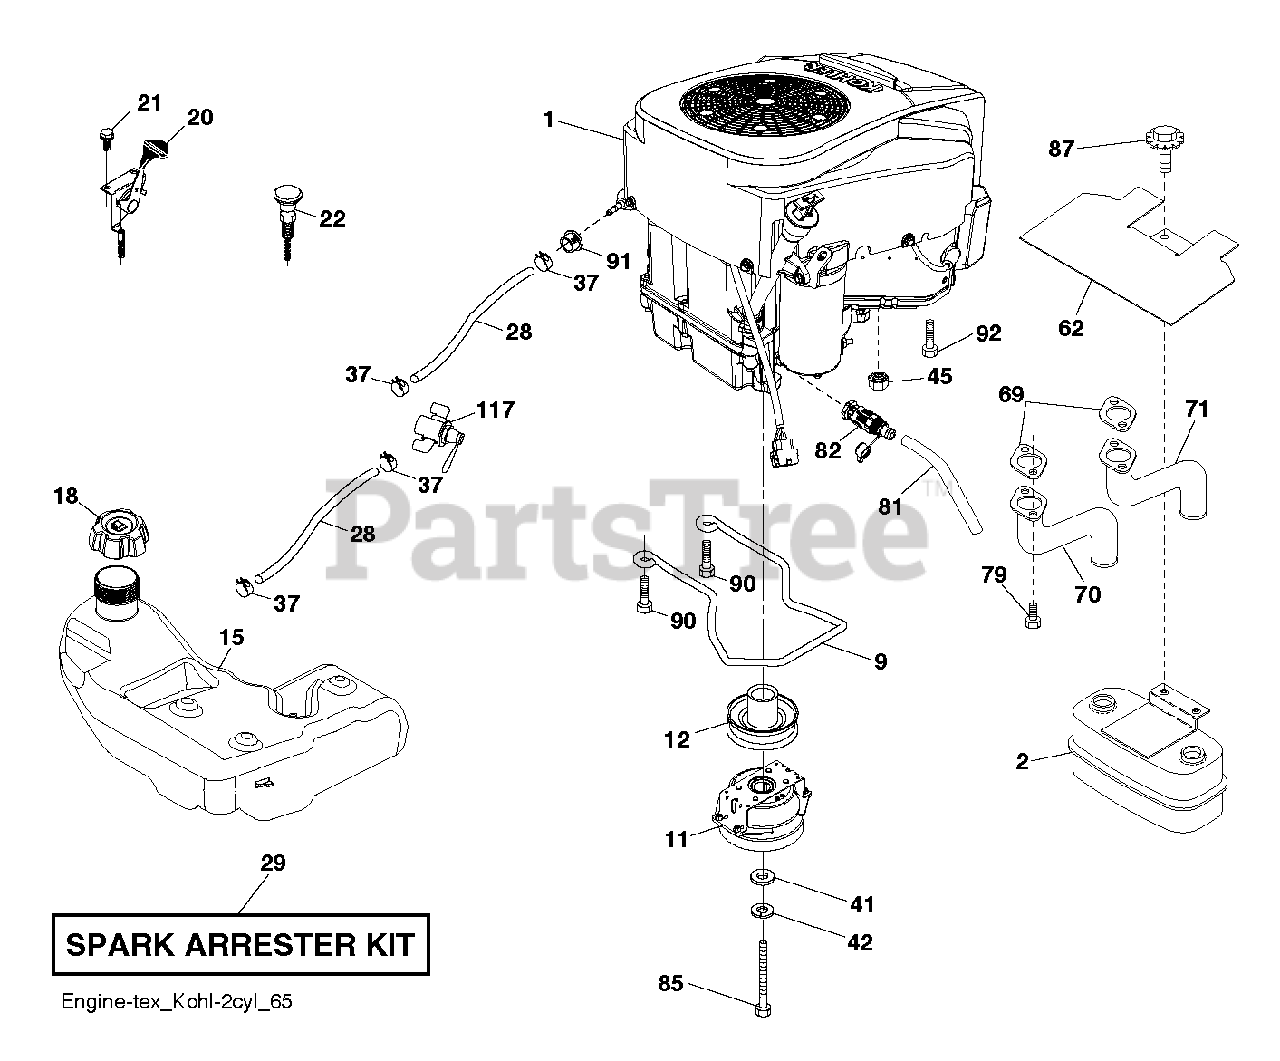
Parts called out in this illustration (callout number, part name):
2	MUFFLER.ASM.TWN.EXTNDED.DFLCTR
9	KEEPER BELT ENGINE
11	CLUTCH.OGURA.5.0PD.GT1.5A-EH01
12	PULLEY ENGINE
15	TANK.ASSY.4.GAL.2.PORT.EPA
18	CAP ASSY FUEL 3" BLACK
20	THROTTLE CONTROL
21	SCREW.#10 X 0.750.BOS
22	CONTROL.CHOKE.ERGO.PUSH-IN.BLA
28	LINE.FUEL.64"REAR.EMIS
29	KIT.SPARK ARRESTOR 794945 B&S
37	HOSE CLAMP
42	LOCKWASHER
45	NUT
62	SHIELD.HEAT.MUFFLER
69	GASKET.EXHAUST.KOHL.CV18-CV26
70	PIPE.EXHAUST.LH.CV18/20
79	SCREW.SOCKET HD.5/16-1
81	TUBE, DRAIN OIL ASM.
82	VALUE.OIL.DRAIN
85	BOLT.HEX.7/16-20X3.0XGR5
87	BOLT.5/16-18UNCX1.W/SEMS.BLK
90	SCREW 3/8-16X1
91	BUSHING.1.375OD
92	SCREW 3/8-16X1
117	VALVE FUEL RESERVE
